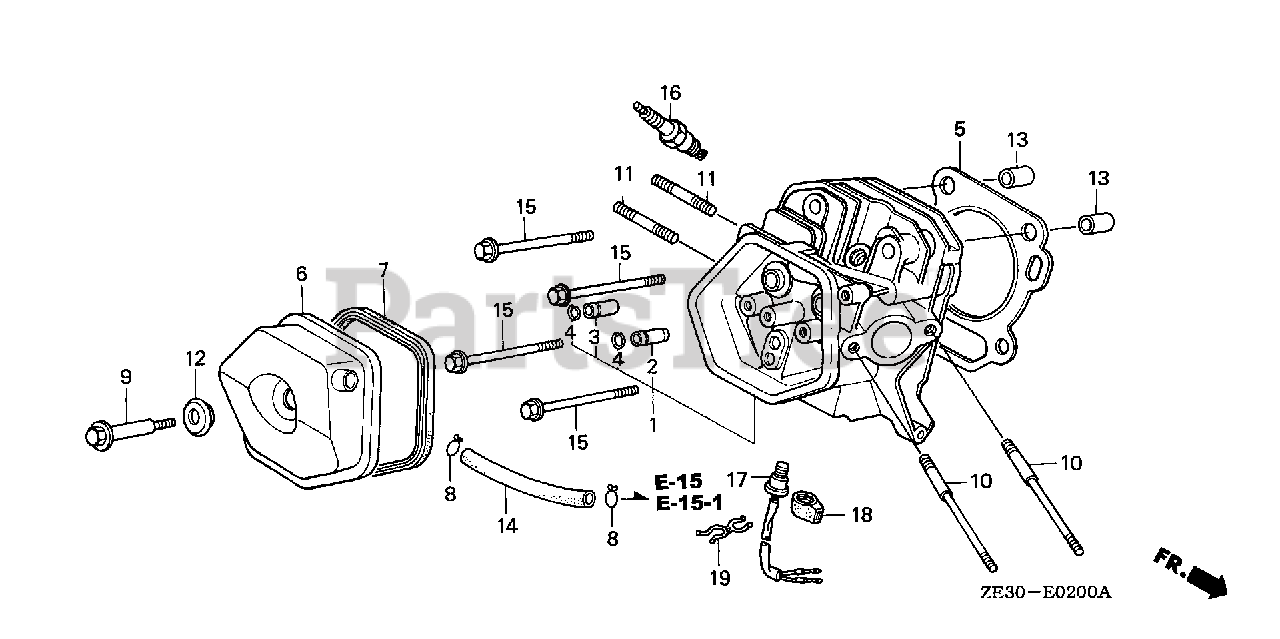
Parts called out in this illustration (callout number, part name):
1	CYLINDER HEAD
1	CYLINDER HEAD (NOT AVAILABLE)
2	GUIDE, VALVE (OVER SIZE)
3	GUIDE, EX. VALVE (OVER SIZE)
4	CLIP, VALVE GUIDE
5	GASKET, CYLINDER HEAD
6	COVER, HEAD
7	GASKET, HEAD COVER
9	BOLT, HEAD COVER
10	BOLT, STUD (8X131.5)
11	BOLT, STUD (8X47)
12	WASHER, HEAD COVER
13	PIN, DOWEL (12X20)
14	BULK HOSE, VACUUM (11X1000) (11X105)
15	BOLT, FLANGE (10X80)
16	SPARK PLUG (BPR5ES-11)
16	SPARK PLUG (W16EPR-U11)
16	SPARK PLUG (BPR6ES-11)
16	SPARK PLUG (W20EPR-U11)
